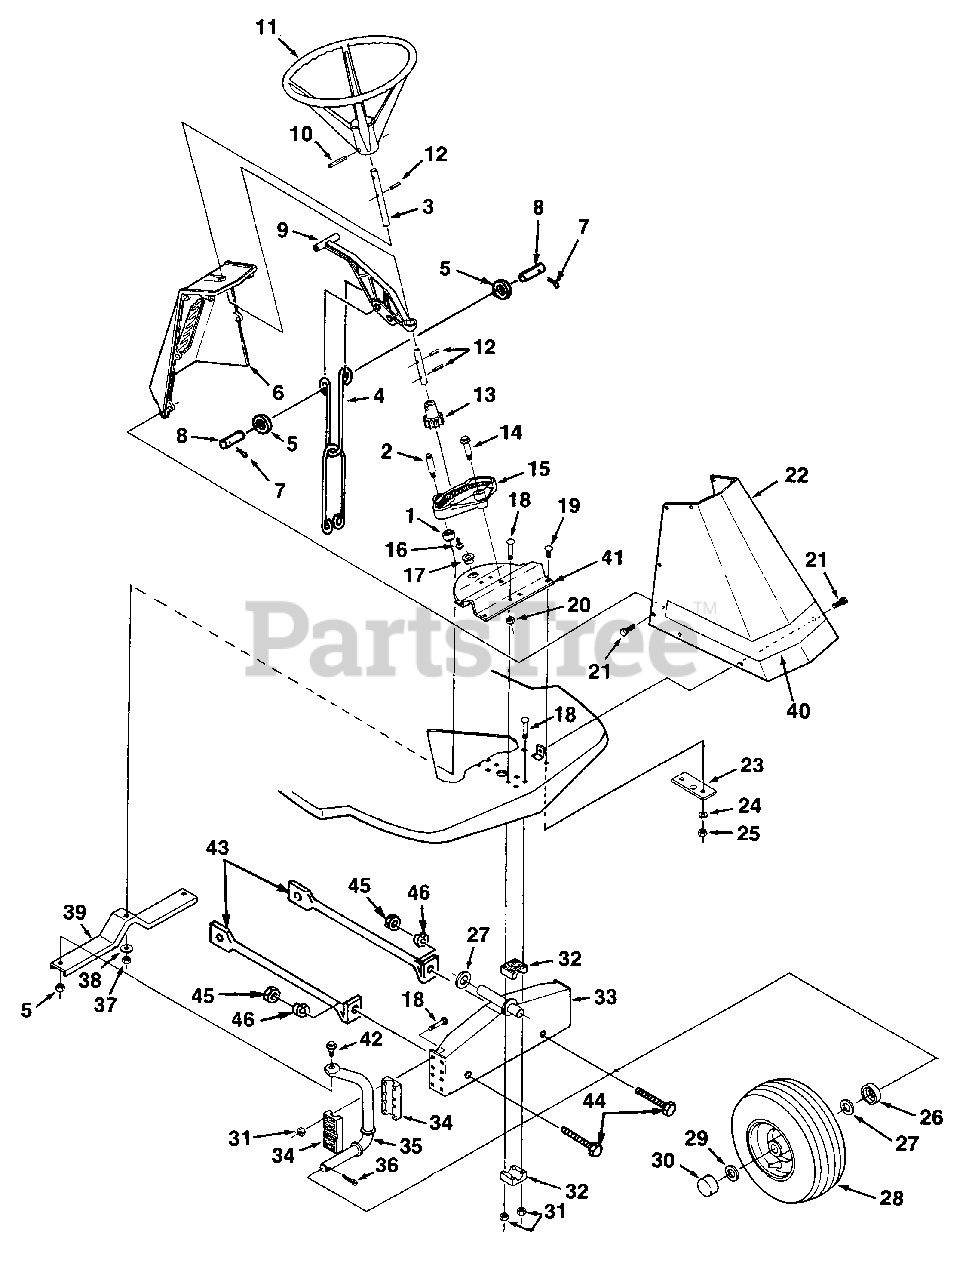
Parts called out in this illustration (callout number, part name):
2	STEER- Stud
4	LINK- Lift
6	PANEL- Console
7	PIN- Cotter
8	PIN- Retainer
9	HANDLE- Lift
11	WHEEL- Steering
15	SECTION- Steering
16	SCREW- 1/4-20 x 1/2
25	NUT
26	WASHER- Dust
28	WHEEL & TIRE
33	AXLE- Front
35	SPINDLE- LH Wheel
38	WASHER
40	DECAL- Product identification
41	BRACKET- Reinforcement
43	SUPPORT- Frame axle
46	WASHER- Lock
